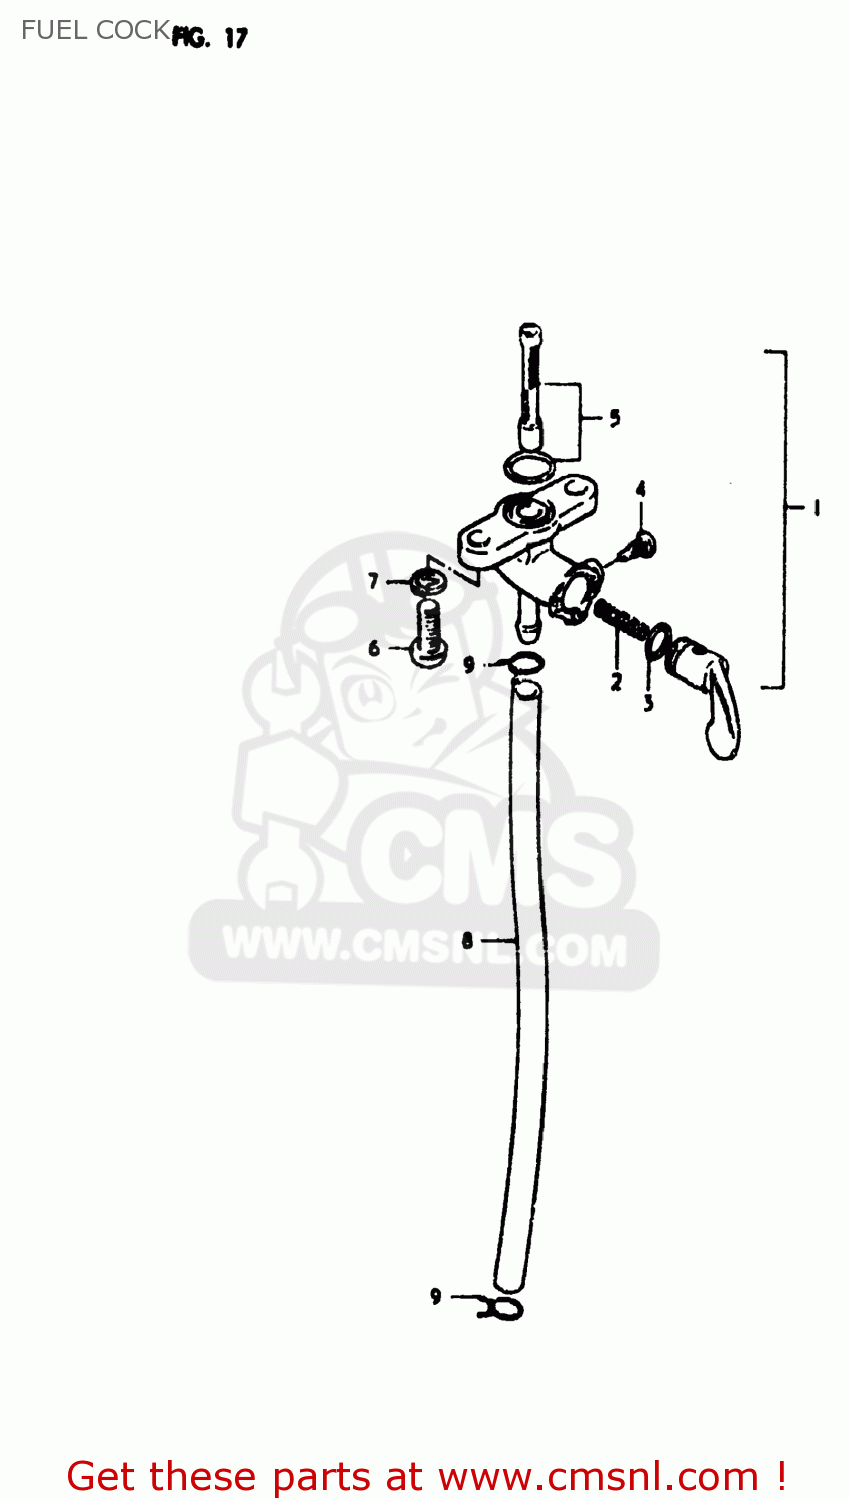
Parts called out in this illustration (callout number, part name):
1	COCK ASSEMBLY,FUEL
2	SPRING,FUEL COCK VALUE
3	O RING,LEVER
4	SCREW
5	FILTER SET FUEL
6	SCREW
7	LOCK WASHER
8	HOSE
9	CLAMP
